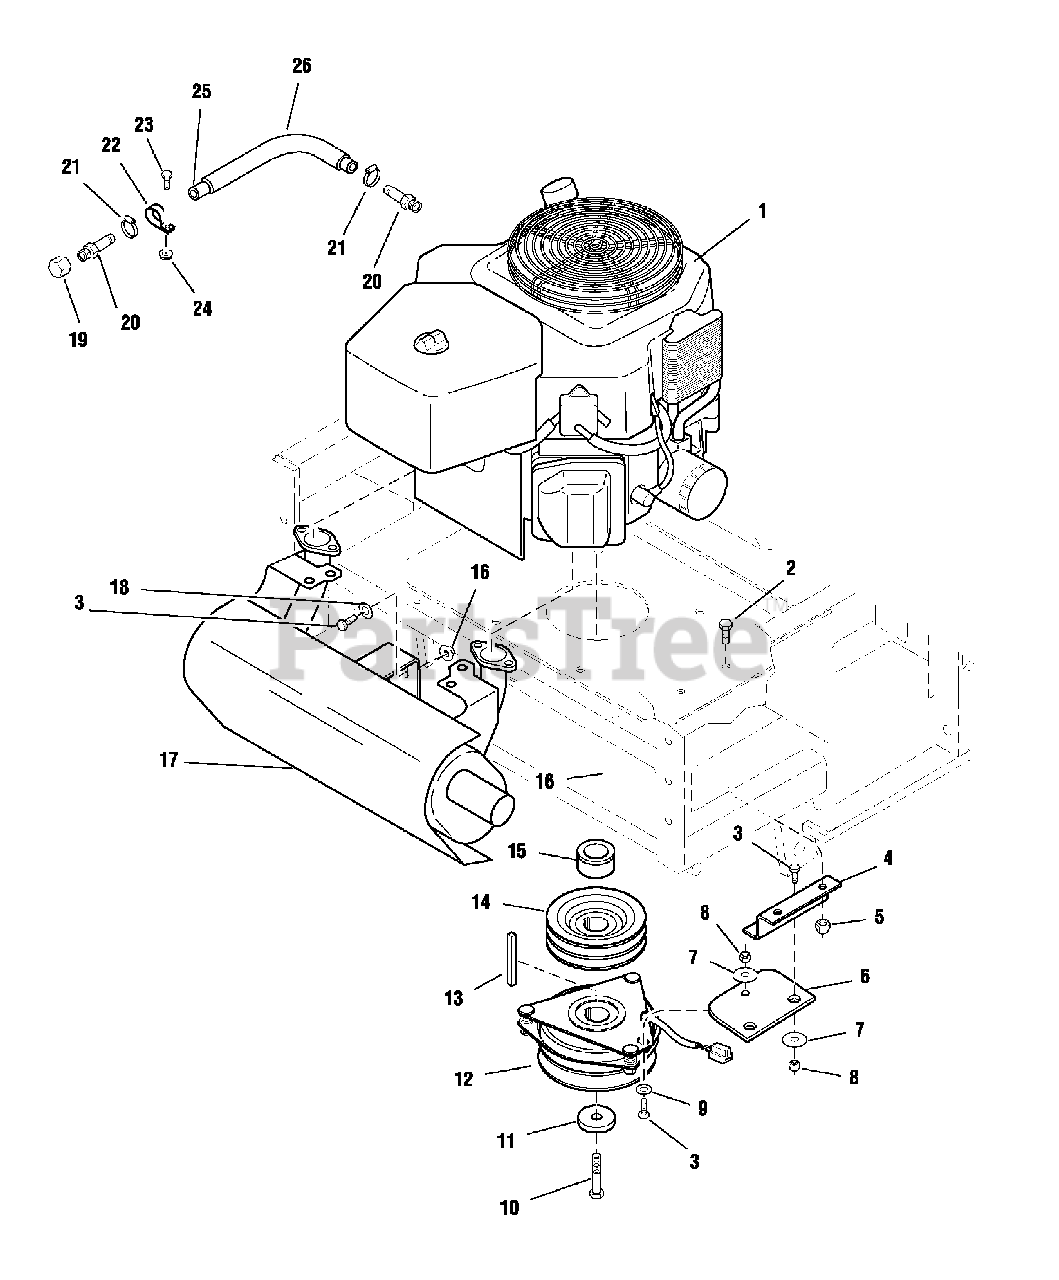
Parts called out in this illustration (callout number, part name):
1	ENGINE, 25HP Kohler
1	ENGINE, 27HP Kohler
1	OIL FILTER
1	PRE-CLEANER
1	AIR FILTER
2	CAPSCREW, Hex Hd, 3/8-16 x 1
3	CAPSCREW, Hex Hd, 5/16-18 x 3/4
4	ANCHOR, CLUTCH - BLK
5	NUT, Hex, Nylon Lock, 3/8-16
6	PAD, Clutch Anchor
7	WASHER, Fender, 5/16
8	NUT, Hex, Nylon Lock, 5/16-18
9	WASHER, 5/16
10	CRANKSHAFT BOLT, 7/16 x 1-3/4
11	SPACER, .45 x 1.88 x .38
12	ELECTRIC CLUTCH
13	KEY, 1/4 Sq. x 3 - 1/2" " LONG
14	CRANKSHAFT PULLEY
15	SPACER, 1.13 x 1.75 x 1.03
16	NUT, Hex, Serrated Flange, 5/16-18
17	MUFFLER
18	WASHER, 5/16
19	CAP, 3/8NPT
20	FITTING, 3/8NPT - 1/2 Str.
22	CLAMP, Vinyl
23	CAPSCREW, Hex Hd, 1/4-20 x 3/4
24	NUT, Hex, Serrated Flange, 1/4-20
26	WIRE LOOM, 12"
